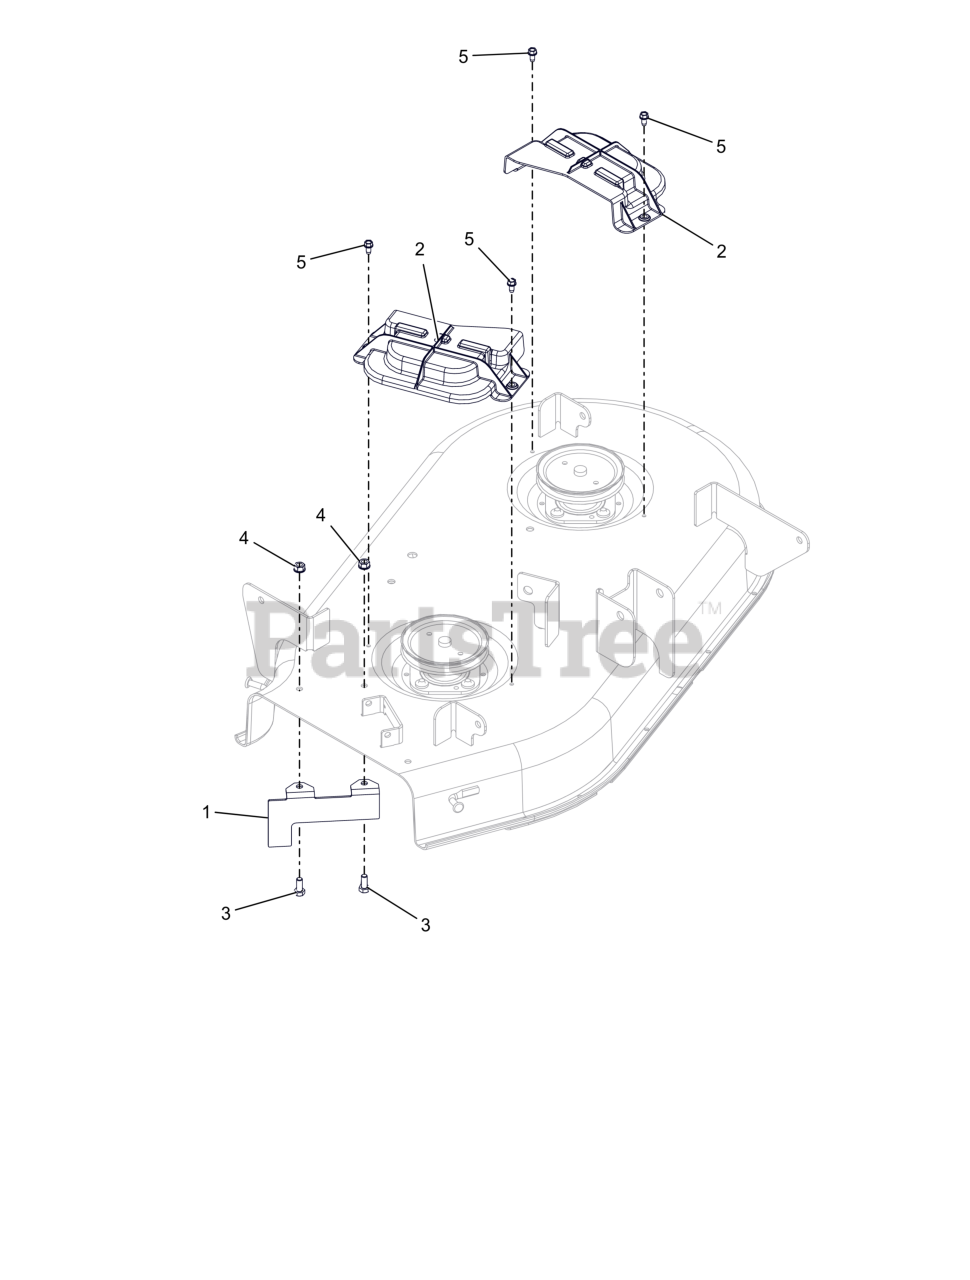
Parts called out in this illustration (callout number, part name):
1	BRKT-BAFFLE, DISCHARGE 34"
2	COVER-BELT, MOLDED
3	BLT,HEX .31-18X.75 G5 ZCC
4	NUT,LK-CTR-FLG .31-18 GF ZCC
5	SCR-TAP .25-20X.50 HWH ZCC
